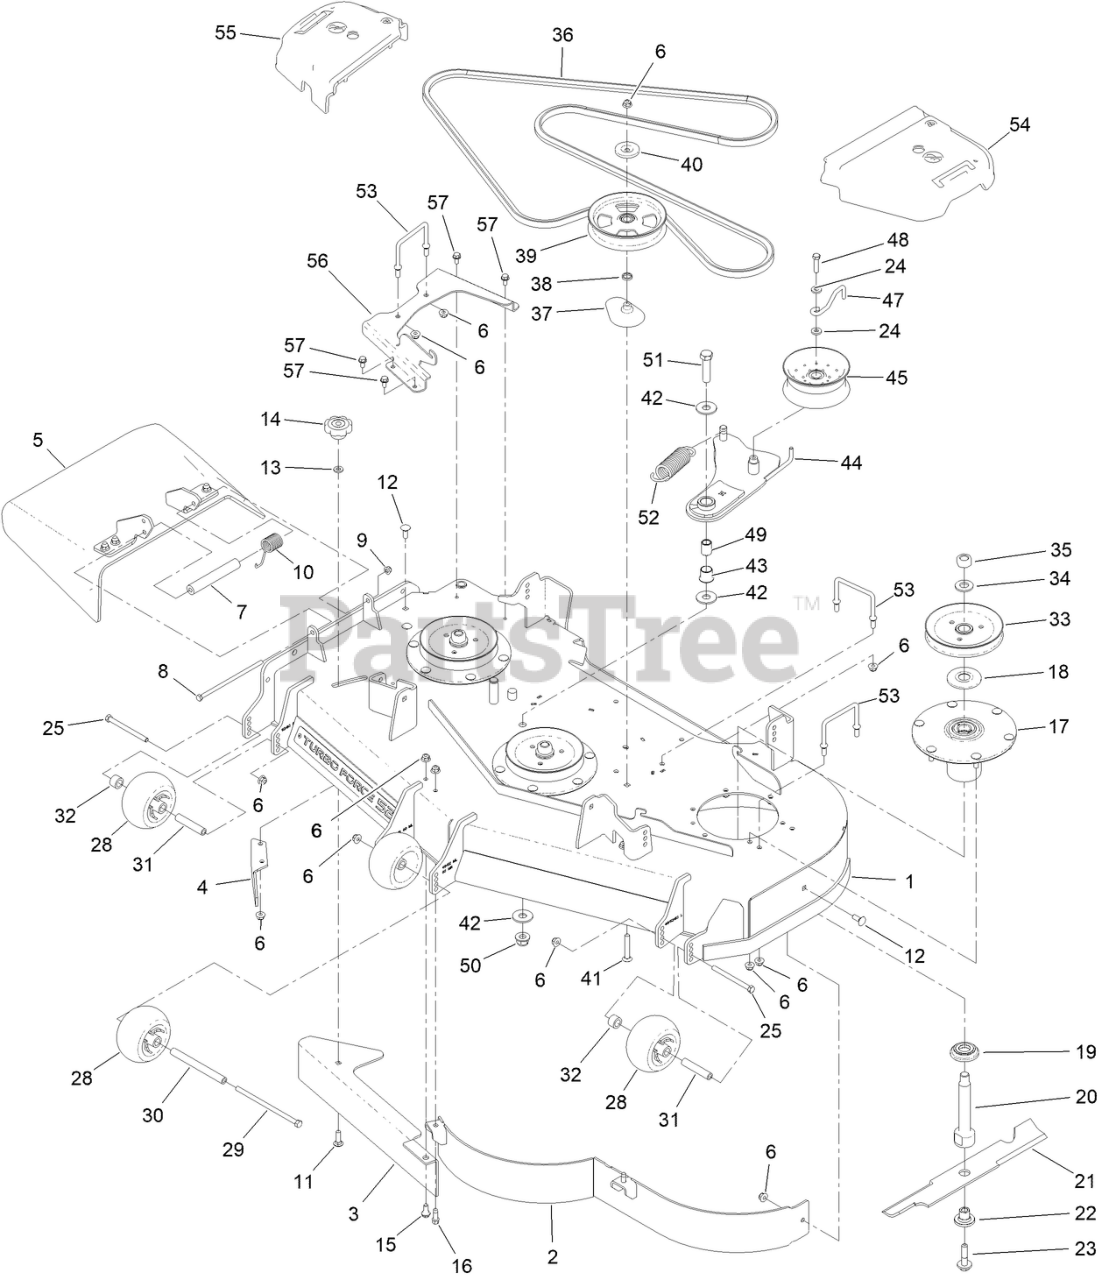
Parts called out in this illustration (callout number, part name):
1	52 DECK ASM W/DECALS
2	BAFFLE-52 INCH
3	PLATE-BAFFLE, FORMED [RED]
4	BAFFLE-DISCHARGE
5	RUBBER DEFLECTOR ASM
6	NUT-HF, NI
7	SPACER
8	SCREW-HH
9	NUT-HF, NI
10	SPRING-TORSION
11	BOLT-CARR
12	BOLT-CARR
13	WASHER-HARDENED
15	BOLT-SHOULDER
17	SPINDLE ASM
18	GUARD-BEARING, TOP
19	GUARD-BOTTOM
20	SHAFT-SPINDLE
21	BLADE-FLOW, HIGH
22	BUSHING-HEX
23	SCREW-SEMS
24	SPACER-HUB, BLOWER
25	SCREW-HH
28	ROLLER-SCALP, ANTI
29	SCREW-HH
30	SPACER-WHEEL
31	TUBE-SHAFTING
32	TUBE-SPACER
33	SHEAVE-BLADE, DRIVE
34	WASHER
35	NUT-HEX
36	BELT 5V-52" DECK
37	SPACER-PULLEY
38	SPACER-PLATE, BBC
39	PULLEY-IDLER, FLAT
40	SHIELD-DUST
41	SCREW-CARR
42	WASHER-FLAT
43	BUSHING, IGUS
44	IDLER ARM ASM [BLACK]
45	IDLER-PULLEY, FLAT
47	WIREFORM BELT GUIDE,IDLER, TOP
48	SCREW-HH
49	BUSHING-IDLER PIVOT
50	NUT-HF
51	SCREW-HH
52	SPRING-EXTENSION
53	WIREFORM-COVER
54	COVER-BELT, LH
55	COVER-BELT, RH
56	PLATFORM-BELT COVER 52
57	SCREW-HWHTF
